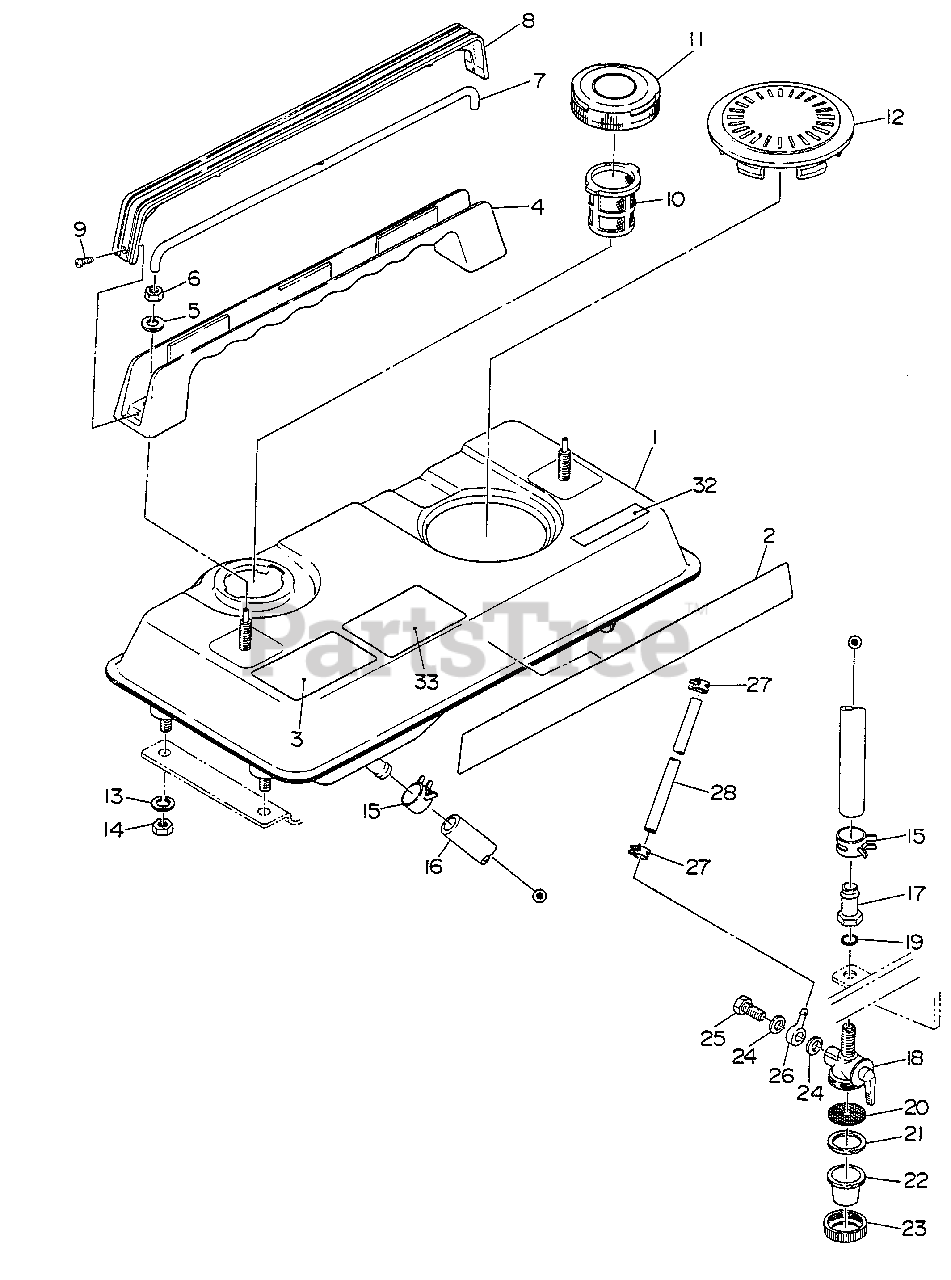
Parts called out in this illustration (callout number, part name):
1	FUEL TANK ASSY
2	LABEL - TRADE MARK
3	LABEL - GENERATOR
4	HANDLE
5	LOCKWASHER
6	NUT
7	PIPE, BREATHER
8	HANDLE COVER
9	SCREW - PAN HEAD
10	FILTER, FUEL
11	CAP ASSY
12	PLUG COVER
13	LOCKWASHER
14	NUT
15	CLAMP, HOSE
16	RUBBER PIPE (11.5×17.5×230 MM)
17	CLAMP, HOSE
18	FILTER, FUEL
19	O-RING
23	NUT, LOCK
24	FIBER PACKING
25	BOLT, BANJO
26	BOLT, BANJO
27	CLAMP, HOSE
28	RUBBER PIPE (6×12×160 MM)
32	LABEL - SPARK ARRESTER
33	LABEL - DANGER
